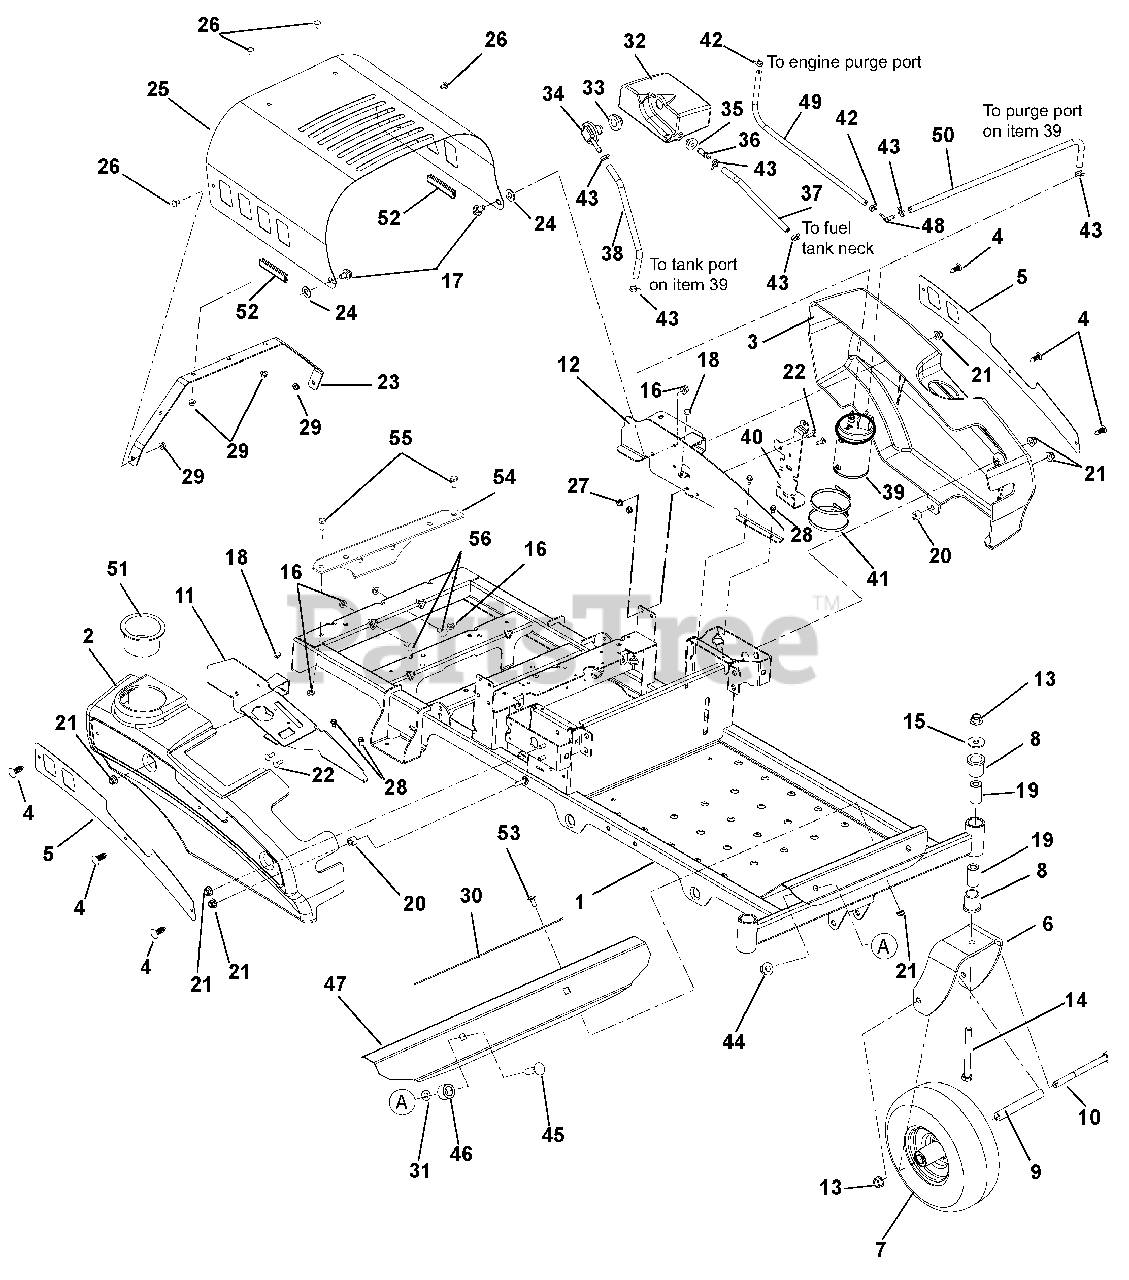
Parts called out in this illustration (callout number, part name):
1	KIT, ZOOM/ZT FRAME W/ DECALS
2	FENDER, RH
3	FENDER, LH
4	RIVET, .25 NYLON PANEL
5	PLATE, FENDER
6	WMT, CASTER FORK
7	TIRE/WHEEL ASSY, 11X4-5
8	BSHG-FLG 1.00X1.25X1.50X1.50
9	SPACER, ROLLED WHEEL
10	@BLT-HEX .50-13X6.50 GR5 YWZC
11	WLDMT, RH FENDER MOUNT
12	WLDMT, LH FENDER MOUNT
13	@NUT-LK-TOP-FLG .50-13 YWZC
14	@BLT-HEX .50-13X5.00 GR5 YWZC
15	WSHR-FL-STL.511X1.441X.125 YWZ
16	@NUT-LK-TOP-FLG .38-16 YWZC
17	BOLT-SHLDR .375-16X.150
18	BUMPER GROMMET
19	SPACER, CASTER .50X1.00X1.84
20	BSHG-SLV .391X.688X.52 PM
21	@NUT-LK-NYL-FLG .31-18 YWZC
22	@BLT-RDHDSQNK .25-20X.75 G5YZ
23	BRACE, HOOD
24	WSHR-FL-NYL .518X1.000X.080
25	HOOD, ZOOM
26	@BLT-RDHDSQNK .25-20X.50 G5YZ
27	@NUT-LK-NYL-FLG .25-20 YWZC
28	@SCR-TAP .25-20X.50 HWH TR YWZ
29	@NUT-LK-TOP-FLG .25-20 YWZC
30	GRIP, ADHESIVE (1" X 16" BLK)
31	NUT-PUSH, .50
32	TANK, FUEL EXPANSION
33	GROMMET, REMOTE VENT NITRILE
34	VALVE, COMBINATION
35	BSHG-FLG .375X1.062X.625 NITR
36	FITTING, STRAIGHT FUEL PLASTIC
37	HOSE, .25 LOW-PERM BULK GAS
38	HOSE, .25 LOW-PERM BULK GAS
39	CARBON CANISTER, 300CC
40	BRKT-MOUNT, CANISTER BBZ
41	P-PLASTIC TIE STRAP LARGE
42	CLAMP-HOSE, SPRING .188
43	CLAMP, FUEL LINE
44	@NUT-LK-NYL-FLG .50-13 YWZC
45	@BLT-RDHDSQNK .50-13X1.75 G5YZ
46	TUBE, UPPER CONTROL PIVOT
47	FOOTREST
48	FITTING-3/16X1/4 90DEGREE VAC
49	HOSE, .188 LOW-PERM BULK GAS
50	HOSE, .25 LOW-PERM BULK GAS
51	CUPHOLDER, SNAP-IN 3.75OD
52	EDGING, CLUTCH PADDLE - 2.00"
53	@BLT-RDHDSQNK .31-18X.75 G5YZ
54	PLATE, BBZ HITCH KIT PLATE
55	@BLT-HEX .38-16X.75 GR5 YWZC
56	@BLT-RDHDSQNK .38-16X.75 G5YZ
